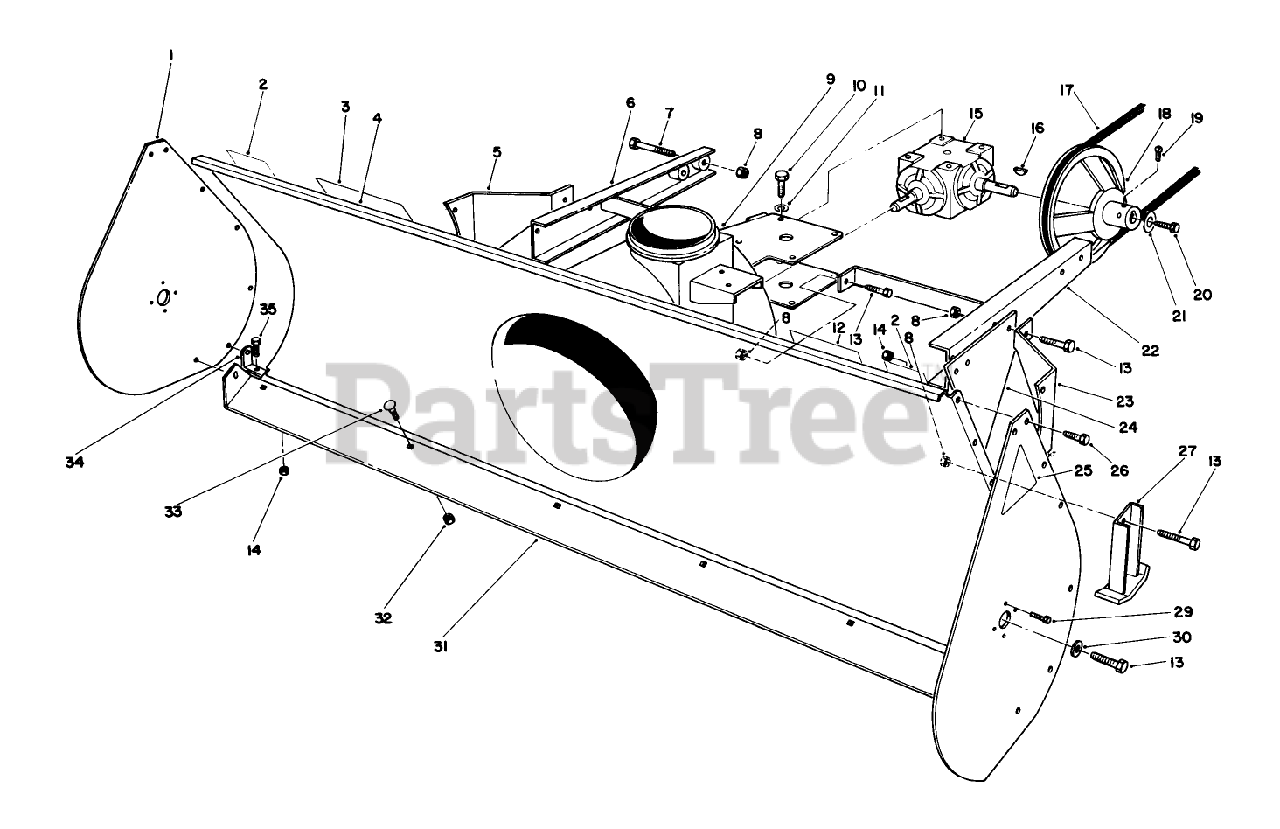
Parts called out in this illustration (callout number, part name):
5	RH EXTENSION PLT *R
6	RH EXT BAR WA *R
7	SCREW-HH
8	NUT-LOCK, NI
9	CHUTE RING
10	SCREW-HH
11	WASHER-LOCK, INTERNAL
13	SCREW-HH
14	NUT-LOCK, NI
15	GEARBOX
16	KEY-WOODRUFF
17	V-BELT
18	DRIVE PULLEY
19	SCREW-SET, SQH
20	BOLT 60183
21	WASHER-FLAT
23	LH EXTENSION PLT *R
24	SKID MTG PLT *R
26	SCREW-HH
29	SCREW-HH
30	WASHER
32	NUT-LOCK, NI
35	SCREW-HH
